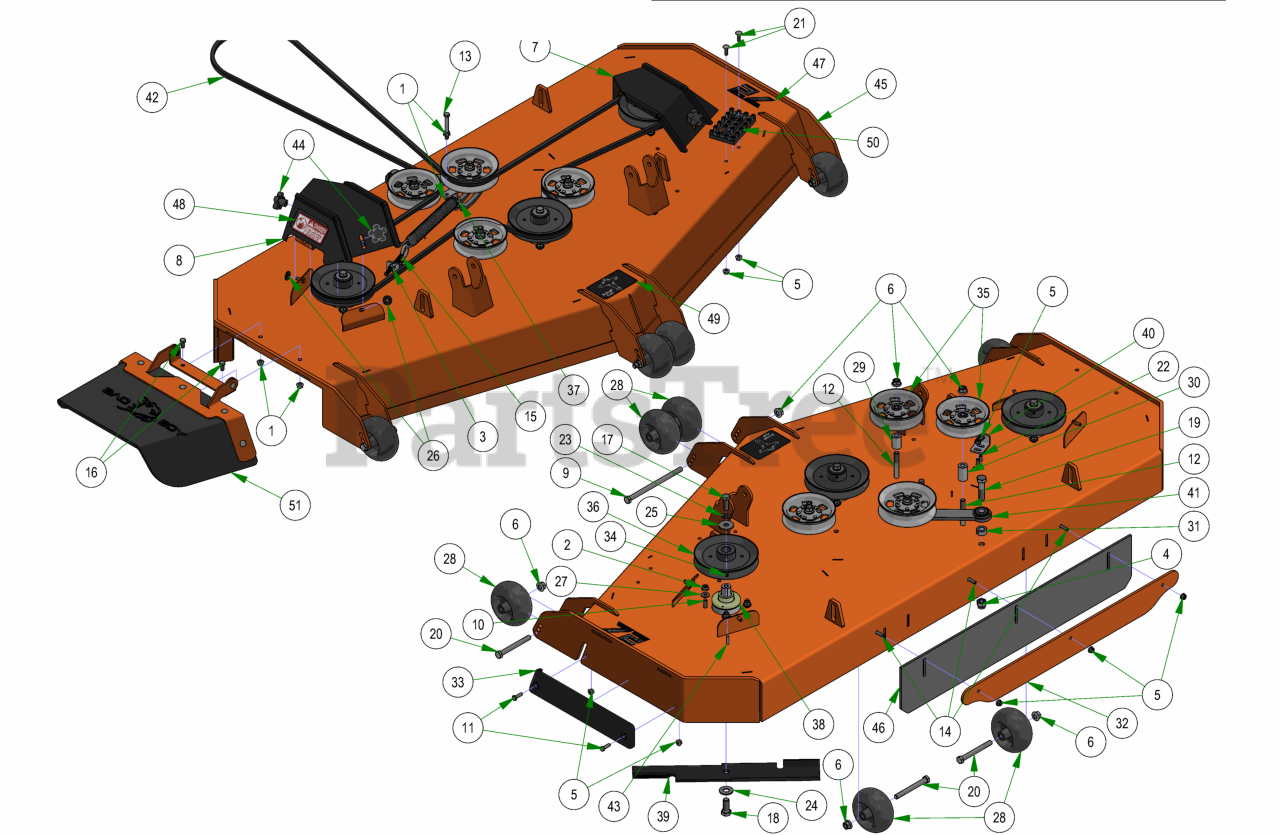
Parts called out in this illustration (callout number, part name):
1	3/8-16 HEX SERRATED FLANGE NUT HARD/ZINC
2	3/8-16 NYLON INSERT FLANGE LOCKNUT (GR.F) ZINC
3	3/8-16 HEX NUT ZINC
4	5/8-11 NYLON INSERT LOCKNUT ZINC
5	5/16-18 NYLON INSERT FLANGE LOCKNUT ZINC
6	1/2-13 NYLON INSERT FLANGE LOCKNUT ZINC
7	2019 72" Left Outlaw Gen2 Pulley Cover
8	2019 72" Right Outlaw Gen2 Pulley Cover
9	1/2-13 X 8 HEX CAP SCREW GR 5 ZINC
10	3/8-16 X 1-3/4 HEX C/S (GR.5) ZC
11	5/16-18 X 1 HEX CAP SCREW (GR.5) ZINC
12	1/2-13 X 3-1/2 HEX FLANGE BOLT (GR.8) ZINC
13	3/8-16 X 3 HEX CAP SCREW (GR.5) ZINC
14	5/16-18 X 1-1/4 CARRIAGE BOLT ZINC
15	4" 3/8-16 Eye Bolt
16	3/8-16 X 3/4 HEX CAP SCREW (GR.5) ZINC
17	1/2-20 X 1-1/2 HEX CAP SCREW (GR.5) ZINC
18	5/8-18 X 1-1/2 HEX CAP SCREW (GR.8) ZINC YELLOW
19	5/8-11 X 2-1/2 HEX CAP SCREW (GR.5) ZINC
20	1/2-13 X 4-1/2 HEX CAP SCREW (GR.5) ZINC
21	5/16-18 X 1 CARRIAGE BOLT (GR.8) ZINC
22	5/16-18 X 7/8 CARRIAGE BOLT ZINC
23	1/2 SPLIT LOCKWASHER (GR.8) ZINC/YELLOW
24	5/8 USS FLAT WASHER (1-3/4" OD) GR.8 ZINC YELLOW
25	1/2 BELLEVILLE WASHER (1-5/8 OD X .140 THK) ZINC
26	.360 ID X .983 OD X .120 THICK FLAT WASHER NYLON BLACK
27	5/16 USS FLAT WASHER (7/8 OD) ZINC
28	2019 Deck Wheel
29	.502 ID X .750 OD X 1.500 Long Spacer
30	1 3/4" Pulley Spacer
31	5/8 SOLID SHAFT COLLAR (W/1 SET SCREW) ZINC
32	61 Bolt in Baffle Deck v2 Stripping Plate
33	REVISED TRIM BUMPER_20180226
34	5/16-24 X 1/4 SOCKET SET SCREW (CUP PT) PLAIN
35	5-3/4 Idler Pulley
36	7" Deck Pulley
37	2019 Outlaw Gen2 Deck Spring
38	OUTLAW SPINDLE ASSEMBLY
39	72" High Lift Fusion Blade
40	2019 Deck Eye Bolt Tab
41	2019 Rebel Rogue Deck Idler
42	B202 Belt for 72" Outlaw
43	1/4 X 1 SQ MACHINERY KEY 1018 STL PLN
44	5/16" Knob
45	2019 Sloped 72" Deck
46	R Series Rubber For Deck
47	72" Deck Decal
48	Danger Decal-Spindle/Discharge
49	2019 Rebel & Rogue Deck Belt Route Decal
50	Deck Step Assembly
51	2019 Outlaw Gen2 Chute Assembly
